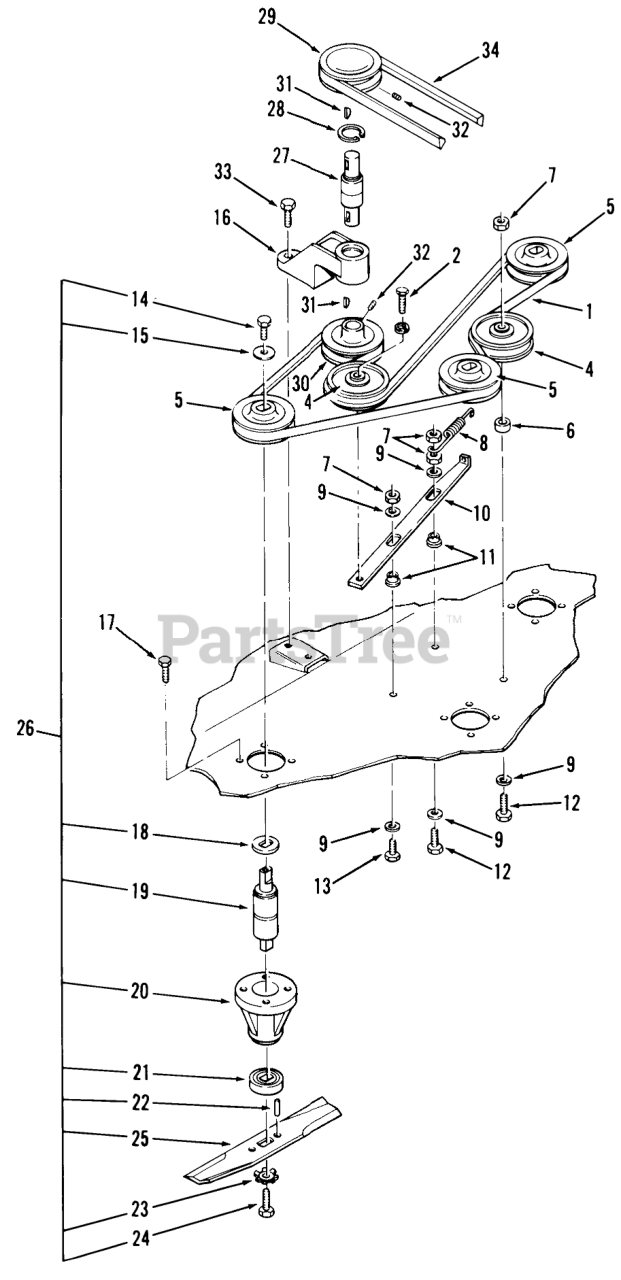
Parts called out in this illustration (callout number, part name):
1	BELT-V
2	BOLT HEX SPECIAL
3	LOCKWASHER
4	Idler Pulley
5	PULLEY-MOWER DRIVE
6	SPACER
7	Nut
8	SPRING-EXTENSION
9	WASHER
10	BAR-IDLER SUPPORT
11	Bushing/Spacer
12	Bolt
13	Bolt
14	Bolt
15	WASHER
16	HOUSING DRIVE BRG R
17	Bolt
18	WASHER-DOUBLE D
19	BEARING
20	HOUSING-BEARING B
21	Cup-Spindle
22	SPIROL ROLL PIN
23	WASHER
24	Bolt
25	BLADE KIT
26	S/A SPINDLE ASSY
27	BEARING-INT SHAFT
28	Snap Ring
29	PULLEY
30	Pulley
31	KEY-WOODRUFF
32	Set Screw
33	Bolt
34	V-BELT
